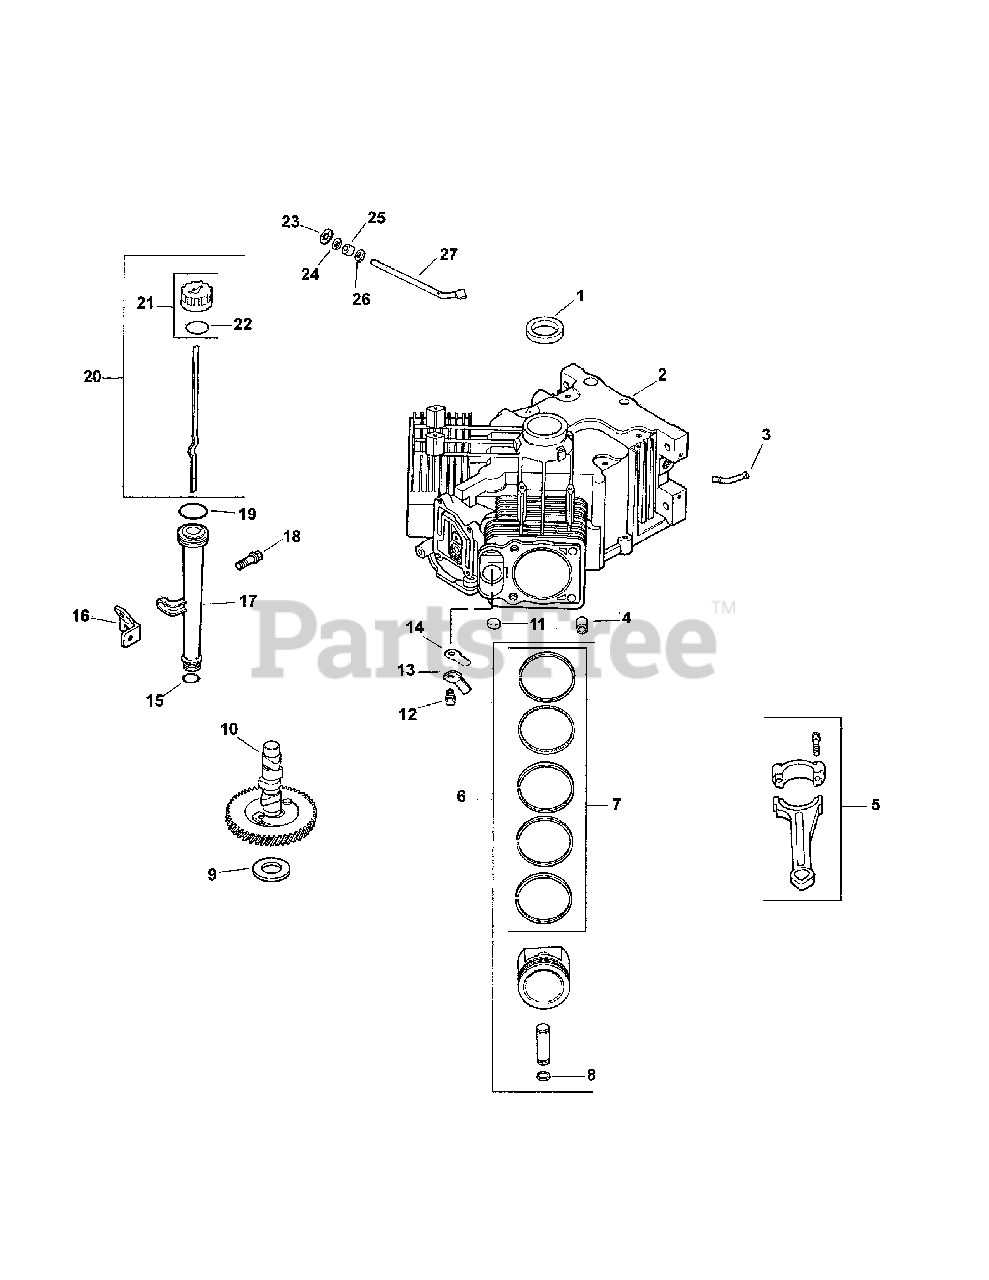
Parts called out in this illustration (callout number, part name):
1	Seal, Oil Front
2	Crankcase
4	Pin, Locating
5	Connecting Rod Std.
5	Connecting Rod .25u/s
6	Piston w/Ring Set Std.
7	Ring Set Std.
8	Retainer, Piston Pin
9	Shim, Camshaft-Red
9	Shim, Camshaft-Black (.04)
9	Shim, Camshaft-White
9	Shim, Camshaft-Blue (.03)
9	Shim, Camshaft-Yellow
9	Shim, Camshaft-Green
9	Shim, Camshaft-Gray
10	Camshaft
12	Screw, Hex Flange M5.0.8x16
13	Retainer, Reed
14	Reed, Breather
15	O-Ring, Lower Oil Fill Tube
16	Bracket, Oil Fill Tube
17	Tube, Oil Fill
18	Screw, Hex Flange M5x0.8x10
19	O-Ring, Upper Oil Fill Tube
20	Dipstick Assembly
21	Kit, Oil Fill Cap
22	O-ring, Dipstick
23	Retainer, Ring
24	Washer, Plain 9mm upper
25	Seal, Governor Cross Shaft
26	Washer, Plain 1/4" lower
27	Shaft, Governor Cross
